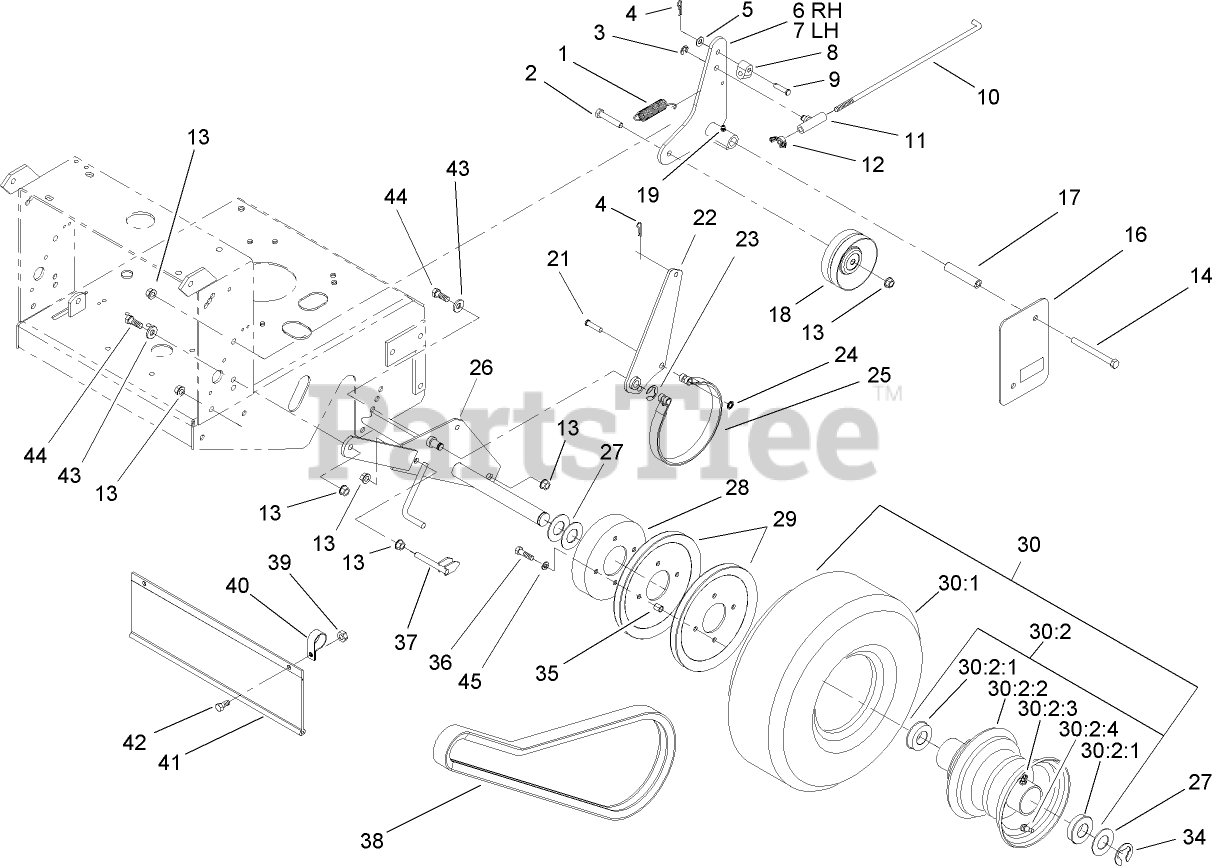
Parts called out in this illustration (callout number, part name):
1	SPRING-EXTENSION
2	SCREW-HH
3	RING-RETAINING
4	PIN-COTTER
5	WASHER-PLAIN
6	RH IDLER ARM ASM
7	LH IDLER ARM ASM
8	FITTING-ROD
9	PIN-CLEVIS
10	ROD-BRAKE
11	SWIVEL-BRAKE
12	WINGNUT-NYLOCK
13	NUT-HHF, WHIZ
14	SCREW-HH
16	SHIELD-WHEEL, DRIVE
17	SPACER-SHIELD
18	IDLER-DRIVE, WHEEL
19	FITTING-GREASE
21	PIN-CLEVIS
22	ARM-BRAKE
23	RING-RETAINING, EXTERNAL
24	NUT-PUSH
25	BAND-BRAKE
27	WASHER-SPACER
28	DRUM-BRAKE
29	SHEAVE-WHEEL, DRIVE
30	WHEEL AND TIRE ASM
30:1	Tire-Turfmaster
30:2	WHEEL AND HUB ASM
30:2:1	BEARING-FLANGED
30:2:2	Rim ASM
30:2:3	Fitting-Grease
30:2:4	Stem-Valve
34	RING-SNAP
35	SPACER-SHEAVE, WHEEL
36	SCREW-HH
37	SCRAPER
38	V-BELT
39	NUT-LOCK, NI
40	CLAMP-R
41	SHIELD-TRAILING
42	SCREW-HH
43	WASHER-BELLEVILLE
44	SCREW-HH
45	WASHER
